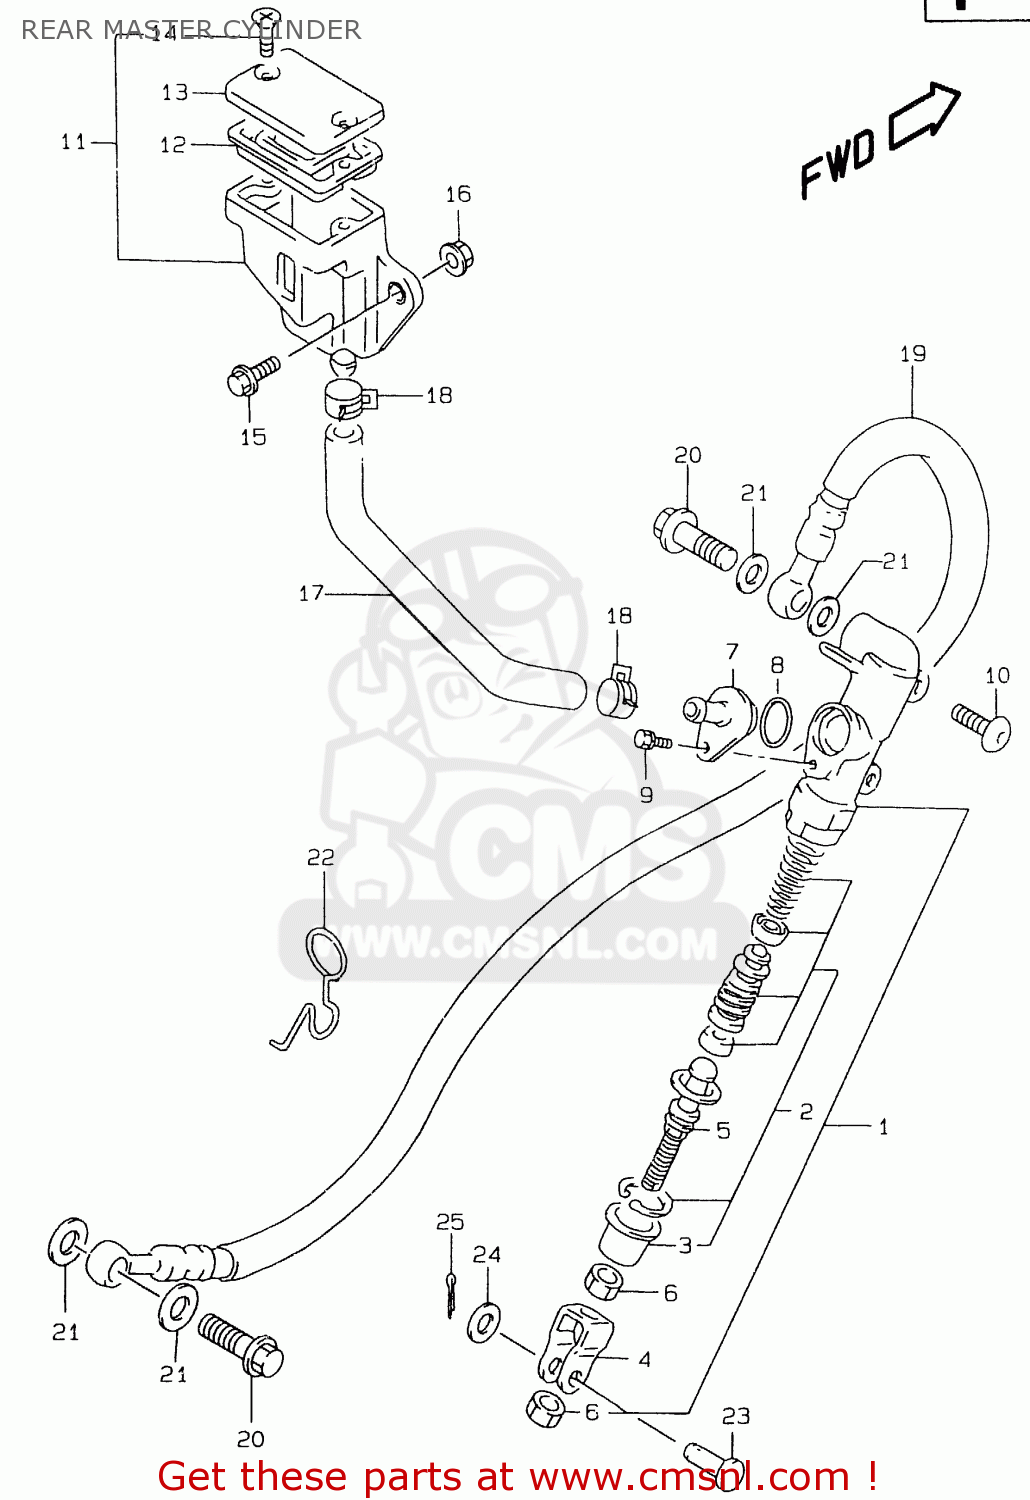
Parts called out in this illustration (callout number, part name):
1	CYLINDER ASSY,RR MASTER
2	PISTON/CUP SET
3	BOOT
4	YOKE
5	ROD,PUSH
6	NUT
7	CONNECTOR
8	O RING
9	SCREW
10	SCREW(6X25)
11	TANK ASSY,RR RESERVOIR
12	DIAPHRAGM
13	CAP
14	SCREW
15	BOLT
16	NUT
17	HOSE,RESERVOIR TANK
18	CLIP
19	HOSE,RR BRAKE
20	BOLT UNION
21	WASHER(10X15X1.5)
22	GUIDE,RR BRAKE HOSE
23	PIN
24	WASHER
25	PIN
